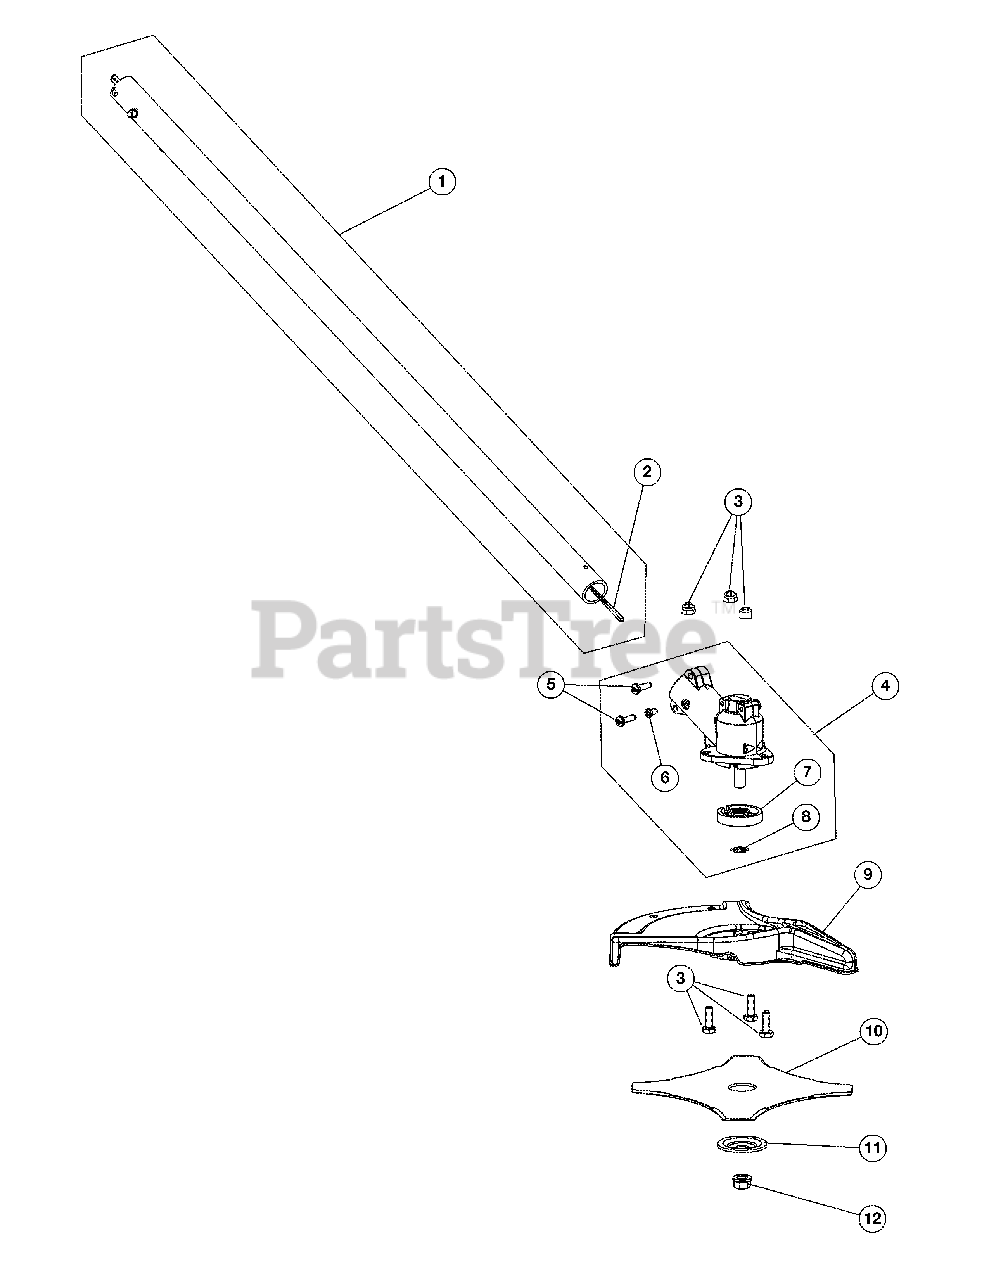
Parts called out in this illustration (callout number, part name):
1	Lower Drive Shaft Housing Assembly (Incl. Ref No. 2)
2	Lower Flexible Drive Shaft
3	Shield Mount Screw Assembly
4	2-Piece Gear Box Assembly (Incl. Ref No. 5-8)
5	Gear Box Mounting Hardware
6	Anti-Rotation Screw
7	Blade Driver
8	Palnut
9	Blade Shield/Shield Mount
10	4-Tooth Blade
11	Retaining Washer
